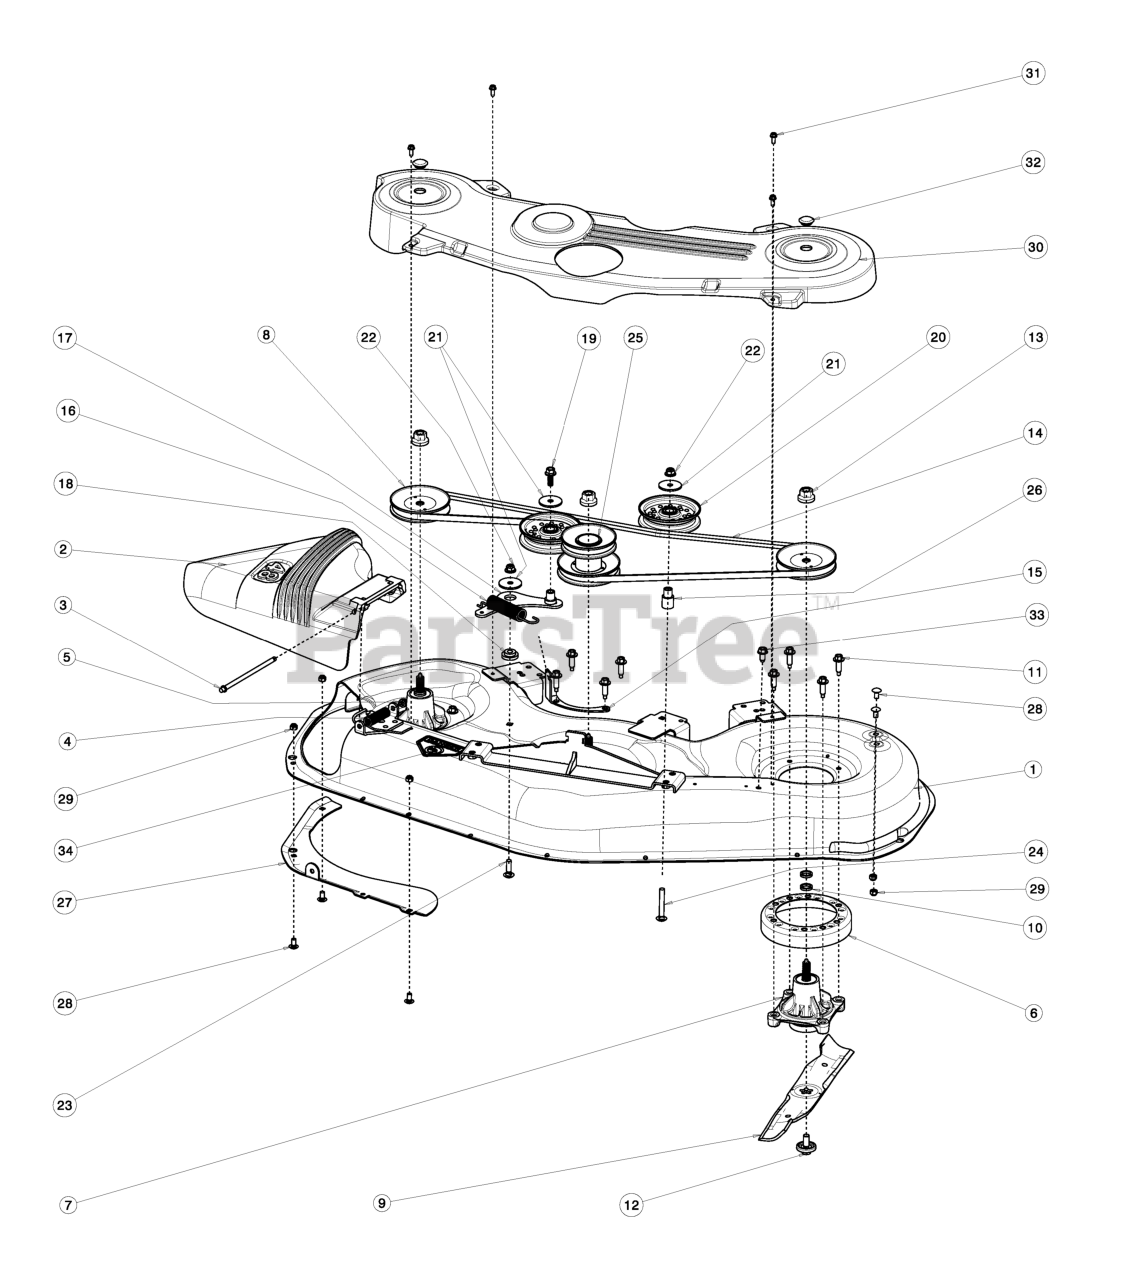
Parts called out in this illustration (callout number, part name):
1	CUTTNG.DECK.48.STMPD.WLDMT.GRE
2	DEFLECTOR.ASM.BLACK.48"
3	ROD.HINGE
4	SPRING, TORSION
5	NUT PUSH M
6	STRIPPER.MANDREL.ROUND.BLACK
7	MANDREL ASM
8	MANDREL.PULLEY.38.BRIGHT.ZINC
9	48" HI-LIFT BLADE
10	WASHER.SPACER.MANDREL
11	SCREW, WASHER HEAD
12	BOLT.WASHER.ASM.7/16-2
13	NUT.FLANGE.LOCK.TOP
14	V-BELT.MOWER.
15	BRCKT.SPRNG.PERCH.MNDRL.MNT.BL
16	SPRING.TENSION
17	ARM.IDLER.WELDMENT.BLACK
18	BUSHING.FLANGE..405
19	HHFS 3/8-16 X 1 GRD 5 ZD
20	IDLER PULLEY
21	WASHER, 3/8 SPEC
22	NUT 3/8-16 HEX FLG NYLOC ZD
23	Carriage Bolt 3/8-16 x 1-1/4
24	Bolt, Carriage 3/8-16 x 2-1/2
25	RP PULLEY.ASSY.STACKED
26	BUSHING.FLANGE
27	BAFFLE, VORTEX MWR
28	Bolt, Carriage 5/16-18 x 5/8
29	Nut, Hex, with Lockwasher Insert 5/16-18
30	SHIELD.BELT.48".STAMPED
31	SCREW.1/4-20X5/8
32	PLUG.HOLE.MANDREL.COVER
33	Screw Hexwsh Thdrol 3/8-16 x 3/4
34	DECAL, CPSC
